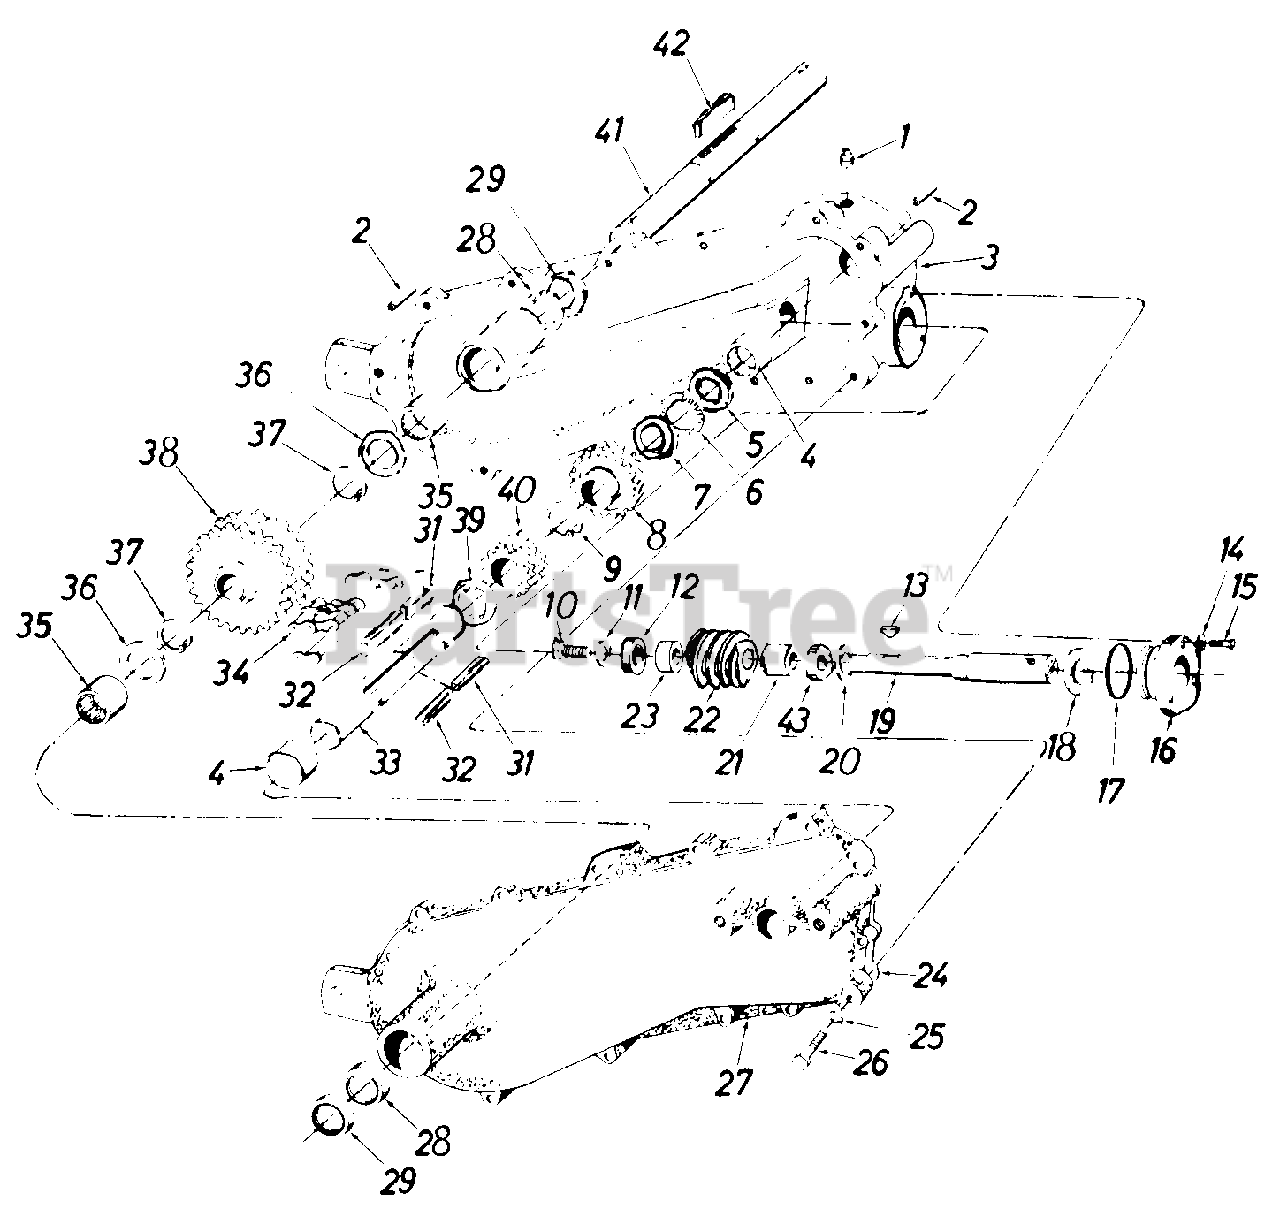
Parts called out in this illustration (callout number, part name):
1	Sq. Hd. Pipe Plug with Vent
2	Spring Pin Spiral 5/16" Dia. x 1.75" Lg.
3	Gear Case-L.H. Half
4	Needle Bearing
5	Thrust Race 1.25" I.D. x .126 Thk
6	Thrust Bearing 1.25" I.D. x 1.977 0. D.
7	Thrust Race 1.25" I.D. x .303 Thk
8	Worm Wheel
9	Snap Ring-for 1.25" Dia. Shaft
10	Hex Lock Scr. 5/16-24 x .75" Lg.
11	Belleville Wash. 5/16" Dia.
12	Ball Bearing .669 I.D. x 1.85 O.D. x .5
13	#9 Hi-Pro-Key 3/16" x 3/4" Dia.
14	L.-Wash. 1/4" Scr.*
15	Hex Scr. 1/4-20 x .88" Lg.*
16	End Cap
17	"O"-Ring
18	Oil Seal .875" I.D. x 1.503 O.D.
19	Worm Input Shaft
20	Fl.-Wash. . 793 1. D . x 1. 240 0 . D .
21	Clutch Idler Bushing
22	Worm Gear
23	Spacer
24	Gasket
25	L.-Wash. 5/16" Scr.*
26	Hex Scr. 5/16-18 x 1.75" Lg.*
27	Gear Case-R.H. Half
28	Oil Seal 1.25" I.D. x 2.004" O.D.
29	Oil Seal 1.25" I.D. x 2.004'.' O.D.
31	Sq. Key 5/16 x 1.25" Lg.*
32	Sq. Key 5/16 x 1.75" Lg.*
33	Worm Gear Shaft
34	Chain w/master link #60 x 39
35	Needle Brg. 1.25" I.D. x 1.927" O.D.
36	Thrust Bearing
37	Tru arc Snap Ring
38	Sprocket-25 Teeth
39	Thrust Bearing
40	Sprocket 13 Tooth
41	Tine Shaft
42	Sq. Key 5/16" x 2.0" Lg.*
43	Ball Bearing.787 I.D. x 2.048 O.D.
